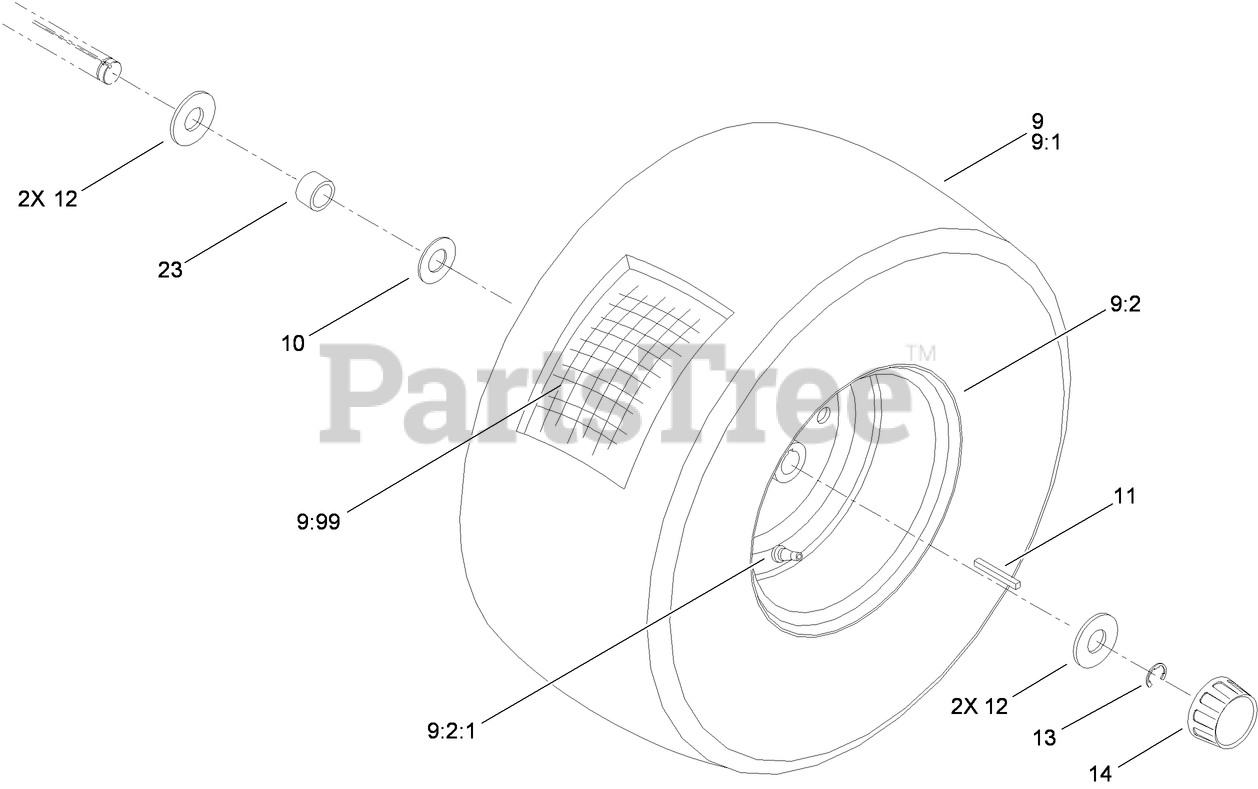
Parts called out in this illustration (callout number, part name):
9	Loose Parts Package
9:1	TIRE
10	WASHER-THRUST
11	KEY-SQUARE
12	WASHER-PLAIN
13	E-RING
14	CAP-HUB
23	SPACER-WHEEL
